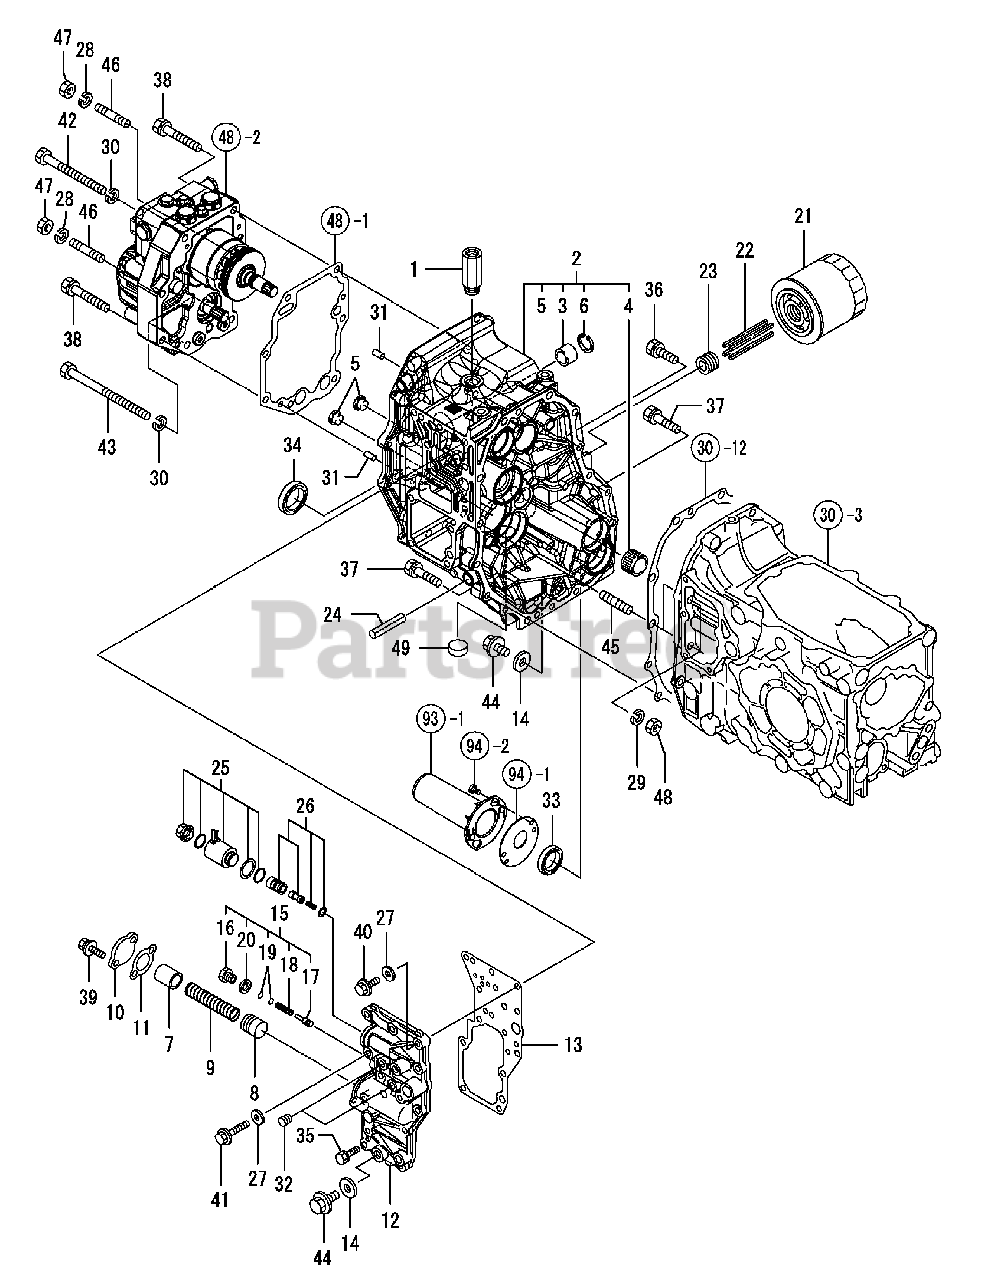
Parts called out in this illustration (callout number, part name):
1	Pipe L,Lub.Oil
2	Housing Assy, Center
3	Dry Bearing 35X20
4	Needle Bearing,2516
11	Packing, Cover Acc
13	Packing,Side Cover L
15	Relief Kit, Pto
21	Filter, Transmission Hydraulic
22	Magnet, Filter
24	Spring Pin 12X60
26	Valve Solenoid Cmp
27	Seal Washer 8(Bolt)
31	Parallel Pin 8X 16
32	Plug Pt1/8,Screw
33	Seal Tc30 42 08, Oil
34	Seal Tc30 47 08, Oil
40	Bolt M 8X 30 Plated
41	Bolt M 8X 55 Plated
42	Bolt M10X110 Plated
43	Bolt M10X135 Plated
45	Stud M10X 45 Plated
46	Stud M10X 55 Plated
